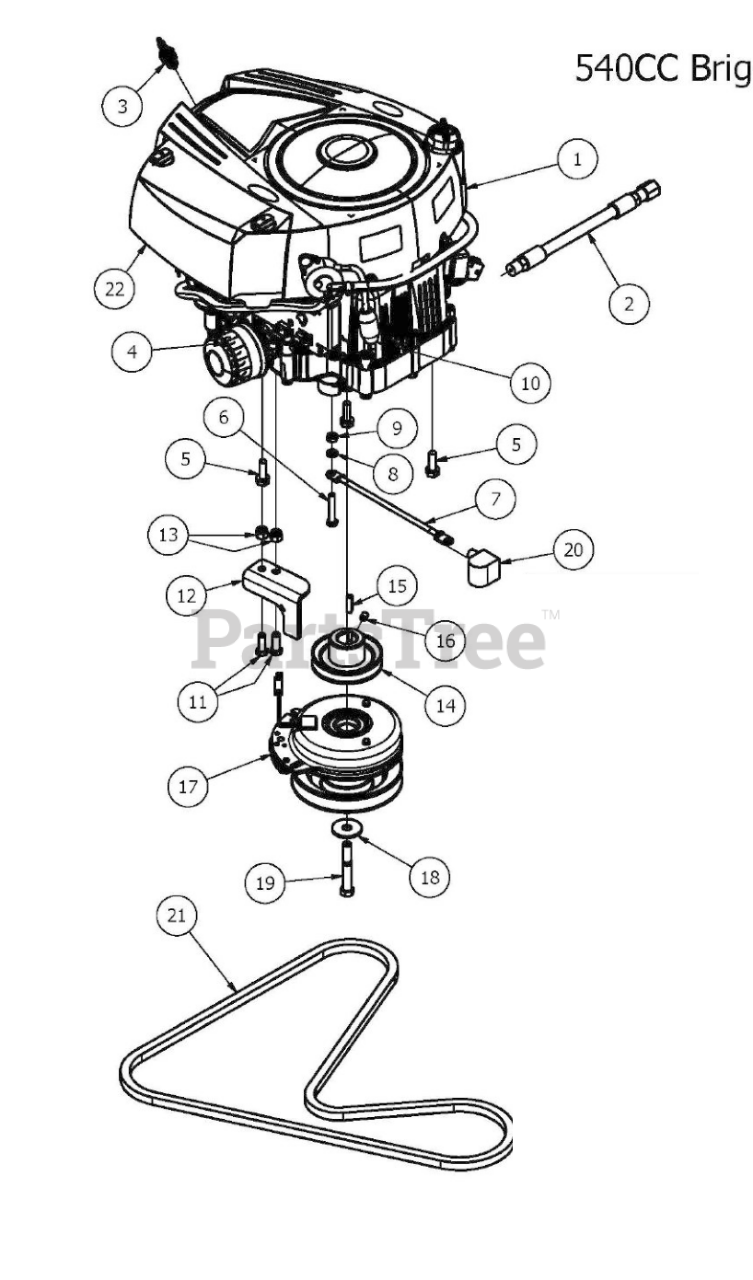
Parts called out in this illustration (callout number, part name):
1	540cc Briggs Intek Engine-MZ
2	Oil drain Hose
3	Spark Plug
4	Briggs Oil Filter
5	3/8 x 1 1/8 bolt
6	5/16" x 1 3/4" Hex Bolt
7	Ground Cable
8	5/16" Lock Washer
10	Universal Inline Fuel Filter
11	3/8" x 1" Hex Bolt
12	2017 MZ Clutch Stop
13	3/8 Nylock Nut
14	3-3/4" Motor Pulley
15	1/4" x 1" Key
16	3/8" Set Screw
17	Clutch 2017 Magnum/MZ
18	1/2 Belleville Washer
19	7/16"-20 x 3" Hex Bolt Gr. 8
20	Black Boot For Ground Cable
22	Air Filter
